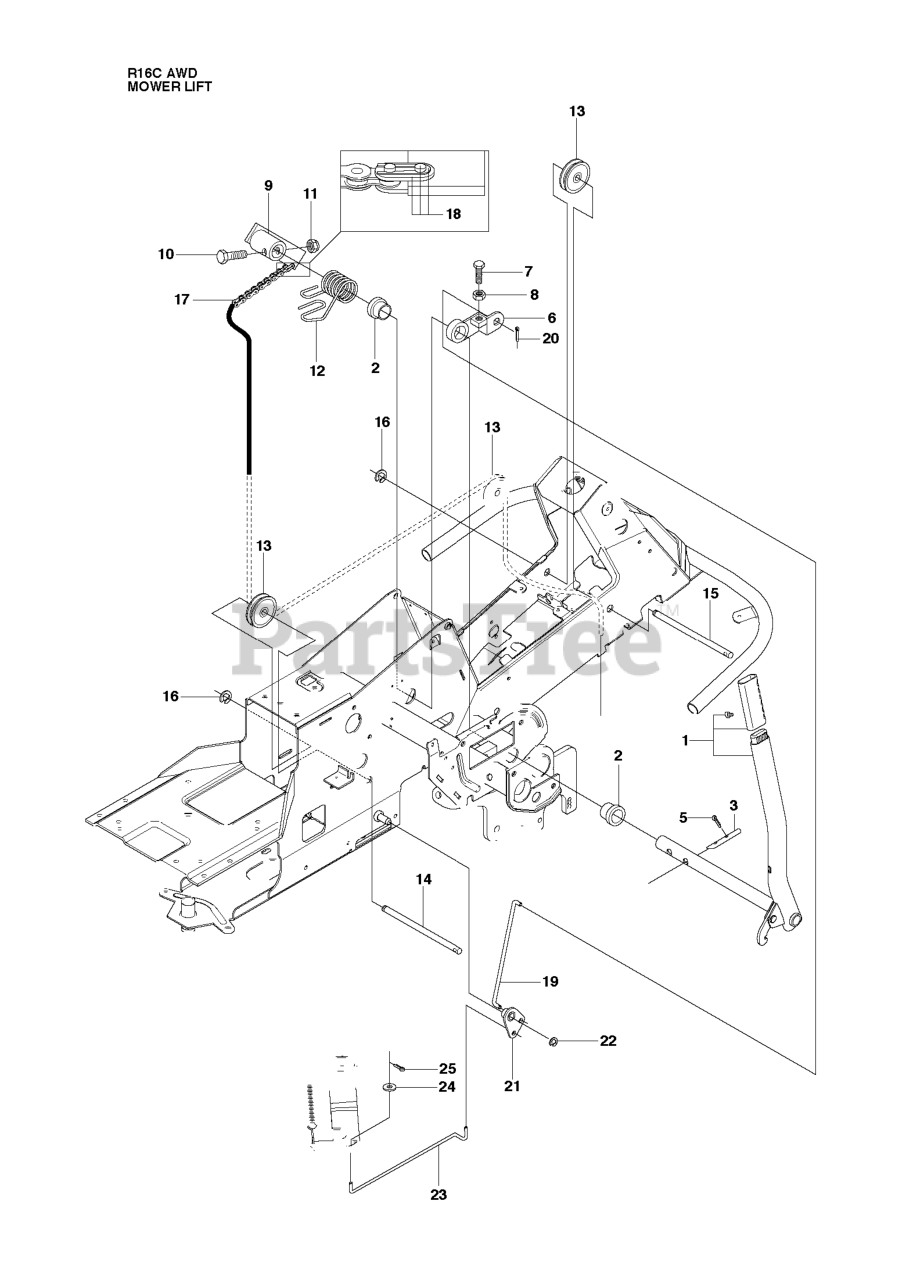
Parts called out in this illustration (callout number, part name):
1	LIFTING LEVER ASSY
2	BEARING FLANGE
6	LEVER CLUTCH
8	NUT
9	LIFTING ARM
19	CONNECTION ROD
22	RETAINING RING
23	CONNECTION ROD
